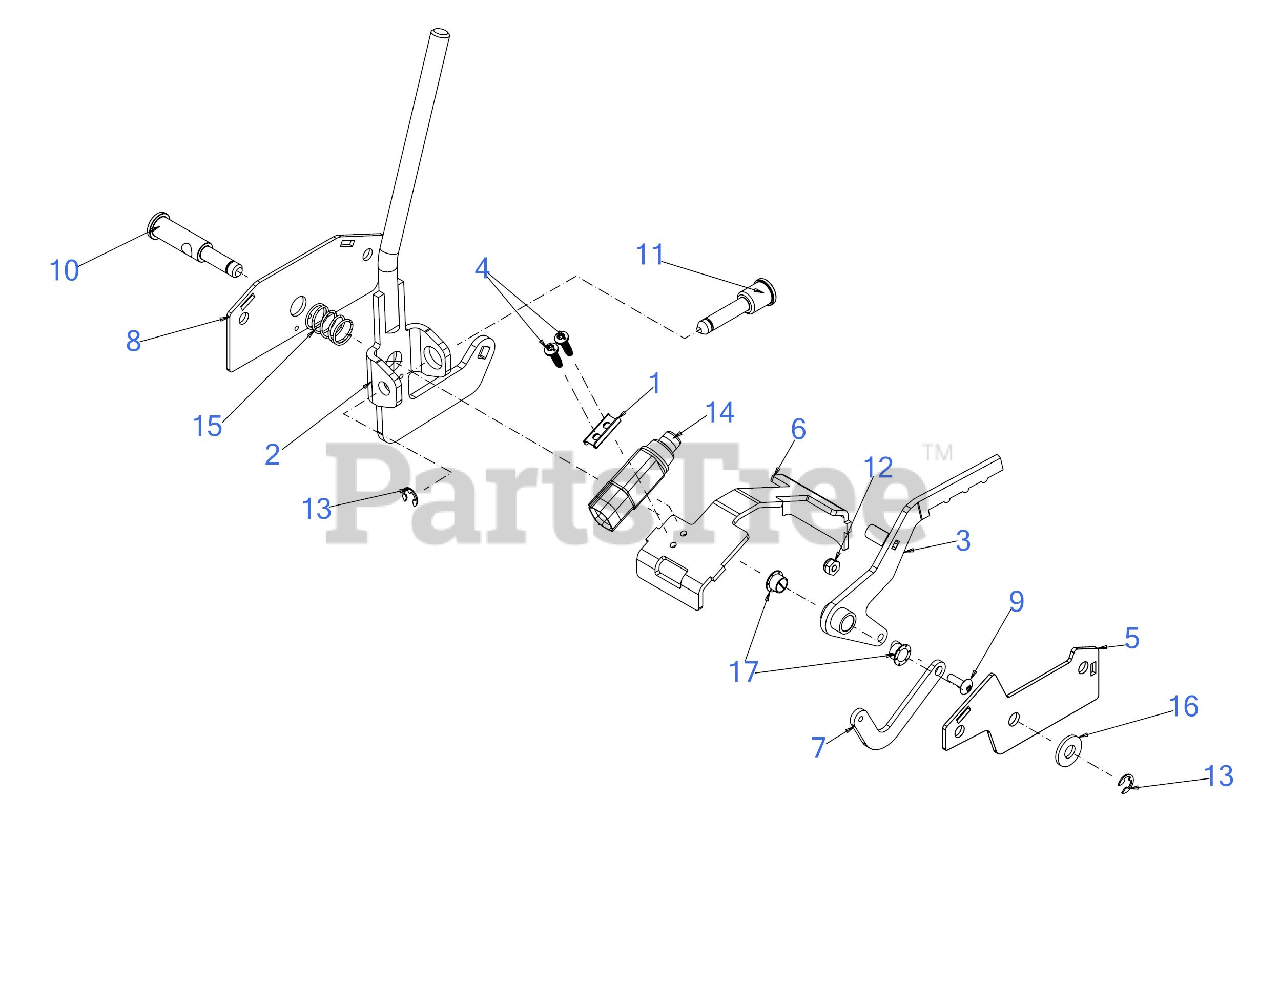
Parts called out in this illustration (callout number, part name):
1	PLATE-SWITCH
2	SHIFT HANDLE
3	DIFF HANDLE
4	SCREW #10-24X11/16:T25
5	SHIFT BRACKET
6	SHIFT BRACKET TOP
7	LINK BRACKET
8	SHIFT PLATE
9	SCREW #10-24 x .62
13	EXTERNAL RETAINING RING 7MM
14	SEALED PLUNGER SWITCH
15	COMPRESSION SPRING
16	FLAT WASHER .385X.870X.090
17	FLANGE BEARING
